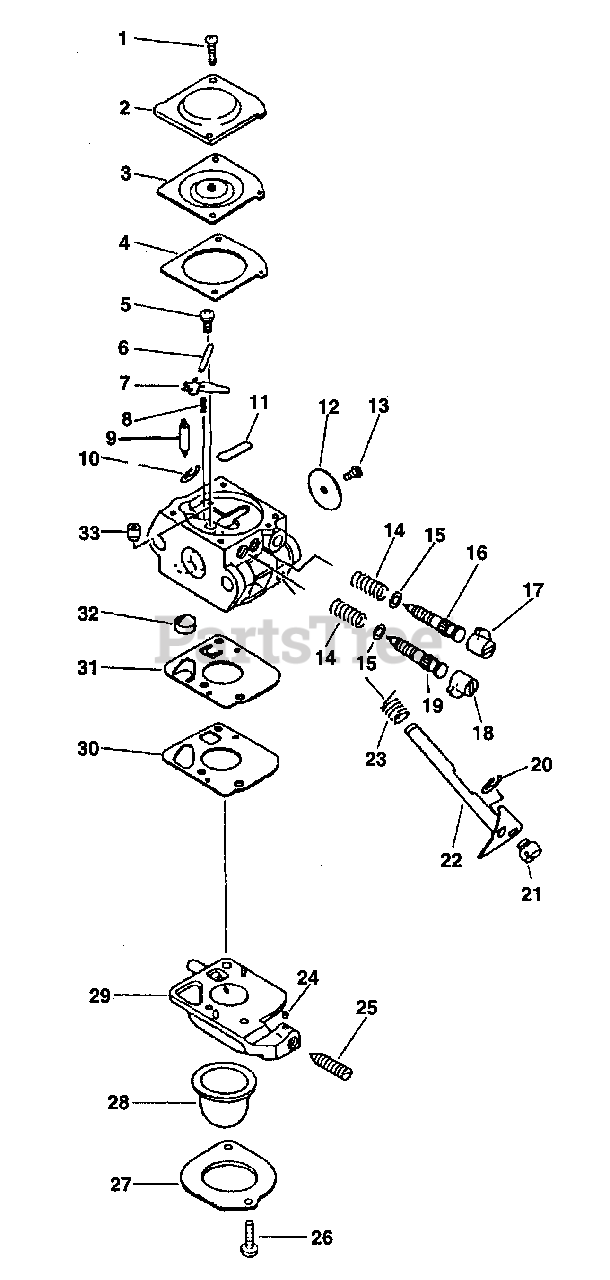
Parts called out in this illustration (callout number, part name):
2	COVER, METERING DIAPHRAGM
3	DIAPHRAGM, METERING
4	GASKET, METERING DIAPHRAGM
7	LEVER, METERING
8	SPRING, METERING LEVER
9	VALVE, INLET NEEDLE
11	PLUG, WELCH
12	VALVE, THROTTLE
14	SPRING, NEEDLE
16	NEEDLE, IDLE
17	CAP, LIMITER - WHITE
18	CAP, LIMITER - RED
19	NEEDLE, HIGH SPEED
22	SHAFT, THROTTLE
23	SPRING, THROTTLE RETURN
24	PIECE, FRICTION
25	SCREW, IDLE ADJUST
27	RETAINER
28	BULB, PURGE
29	BODY ASSY, PURGE
30	GASKET, FUEL PUMP
31	DIAPHRAGM, FUEL PUMP
33	NOZZLE, CHECK VALVE
